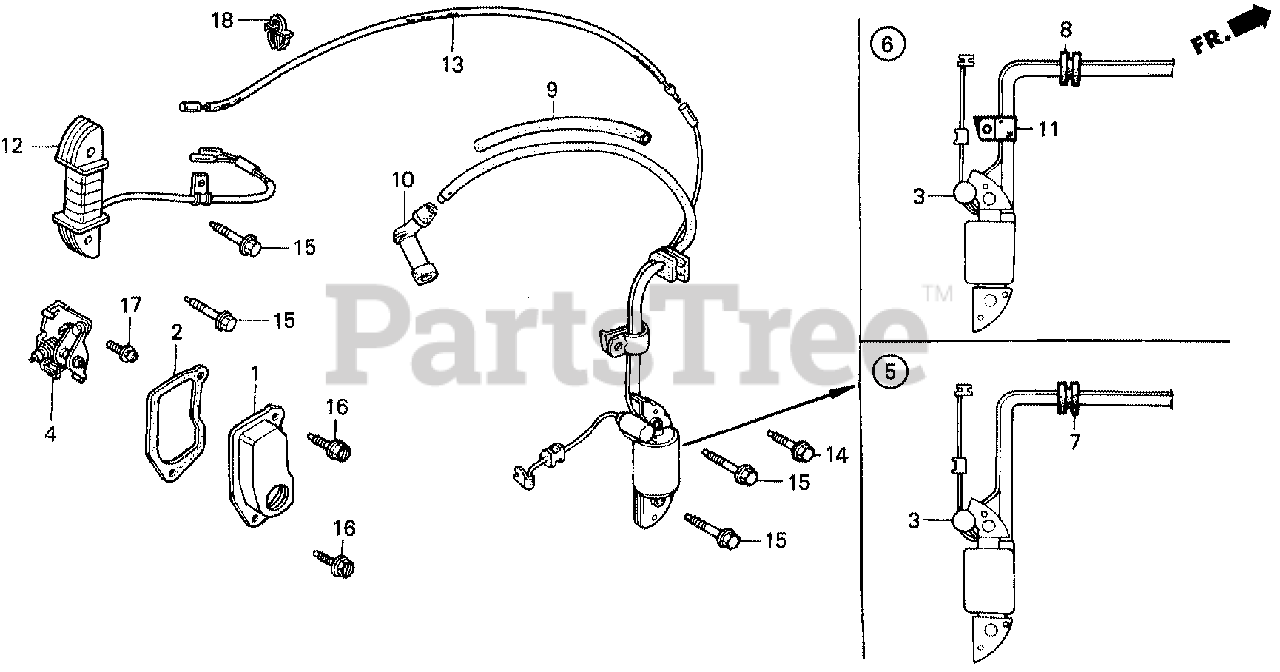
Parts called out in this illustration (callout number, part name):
1	COVER, POINTS
2	GASKET, COVER
3	CONDENSER
4	POINTS ASSY.
6	COIL ASSY., IGNITION (LAMP COIL)
8	GROMMET, WIRE
9	TUBE, IGNITION RUBBER
10	CAP ASSY., NOISE SUPPRESSOR
11	CLAMP, IGNITION WIRE
13	WIRE A, ENGINE STOP
14	BOLT, FLANGE (6X12) (CT200)
15	BOLT, FLANGE (6X32)
16	BOLT, FLANGE (5X10)
17	SCREW-WASHER (5X12)
